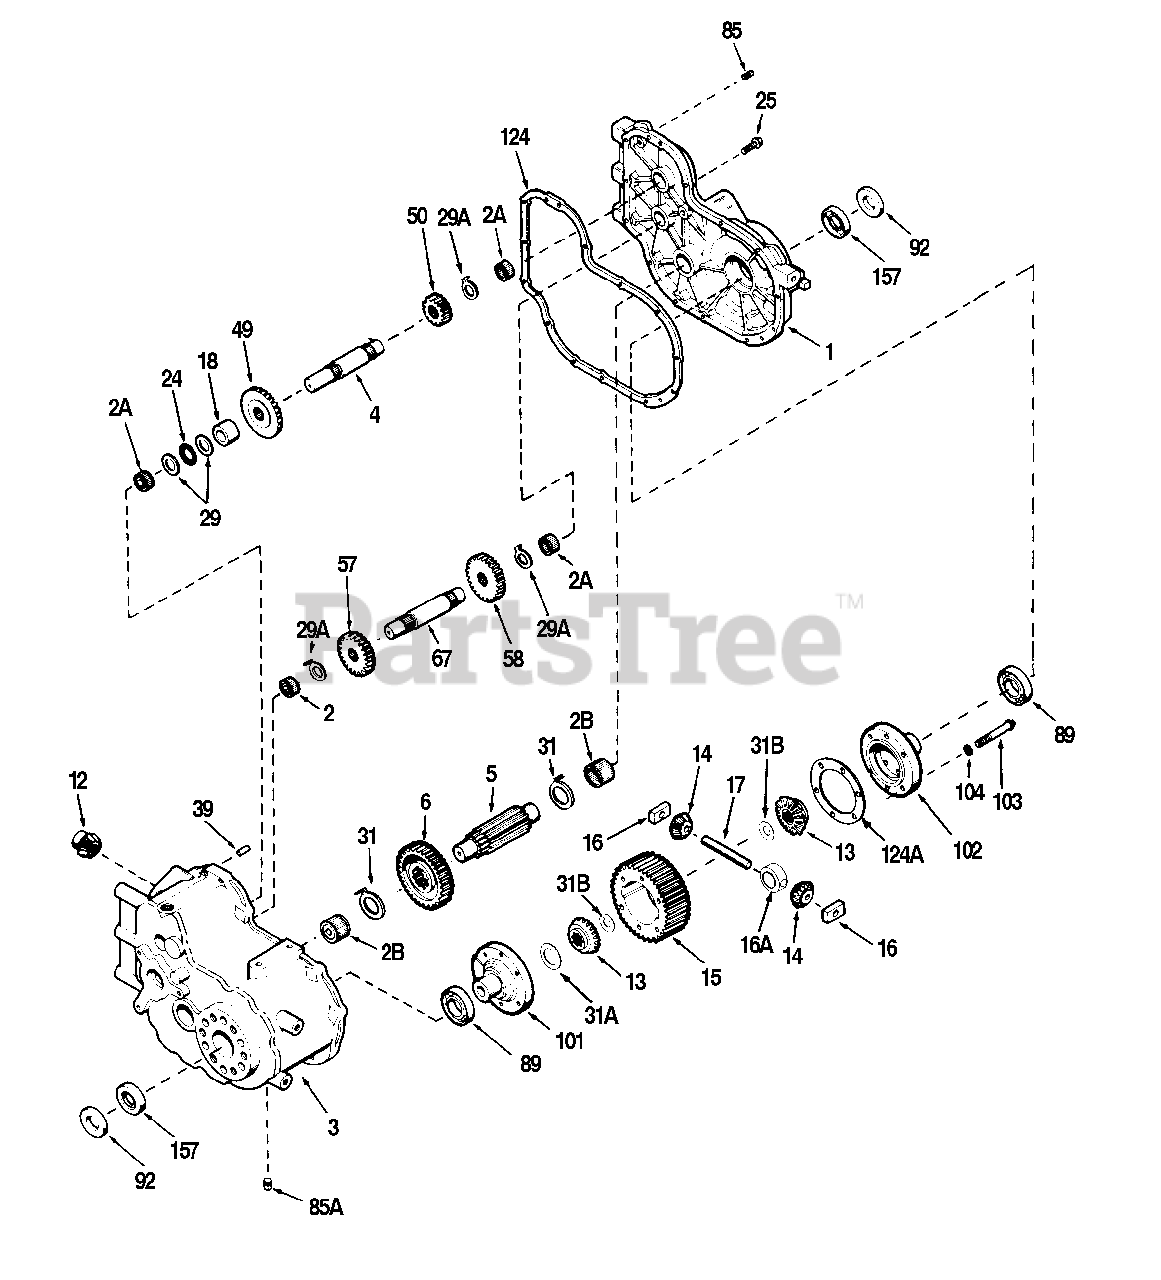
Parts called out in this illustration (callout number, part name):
1	TRANSAXLE COVER
2	NEEDLE BEARING
2A	NEEDLE BEARING
2B	NEEDLE BEARING
3	TRANSAXLE CASE
4	COUNTERSHAFT
5	OUTPUT PINION
6	OUTPUT GEAR (33 teeth)
12	BEVEL PINION
13	BEVEL GEAR (16 teeth)
14	BEVEL PINION (10 teeth)
15	RING GEAR
16	DRIVE BLOCK
16A	SPACER BLOCK
17	DRIVE PIN
24	THRUST BEARING
25	SCREW, 5/16-18 x 1
31B	BELLEVILLE WASHER
39	Dowel Pin
49	Bevel Gear (30 teeth)
50	Spur Gear (16 teeth)
57	Spur Gear (17 teeth)
58	Spur Gear (27 teeth)
67	Brake Shaft
85	Plug, 1/8 - 27
85A	MAGNETIC DRAIN PLUG, 3/8-18
89	Ball Bearing
101	Differential Carrier
102	Differential Carrier
103	Screw, 3/8-16 x 2-3/4
104	Lockwasher, 3/8
157	Oil Seal, 1-1/8
